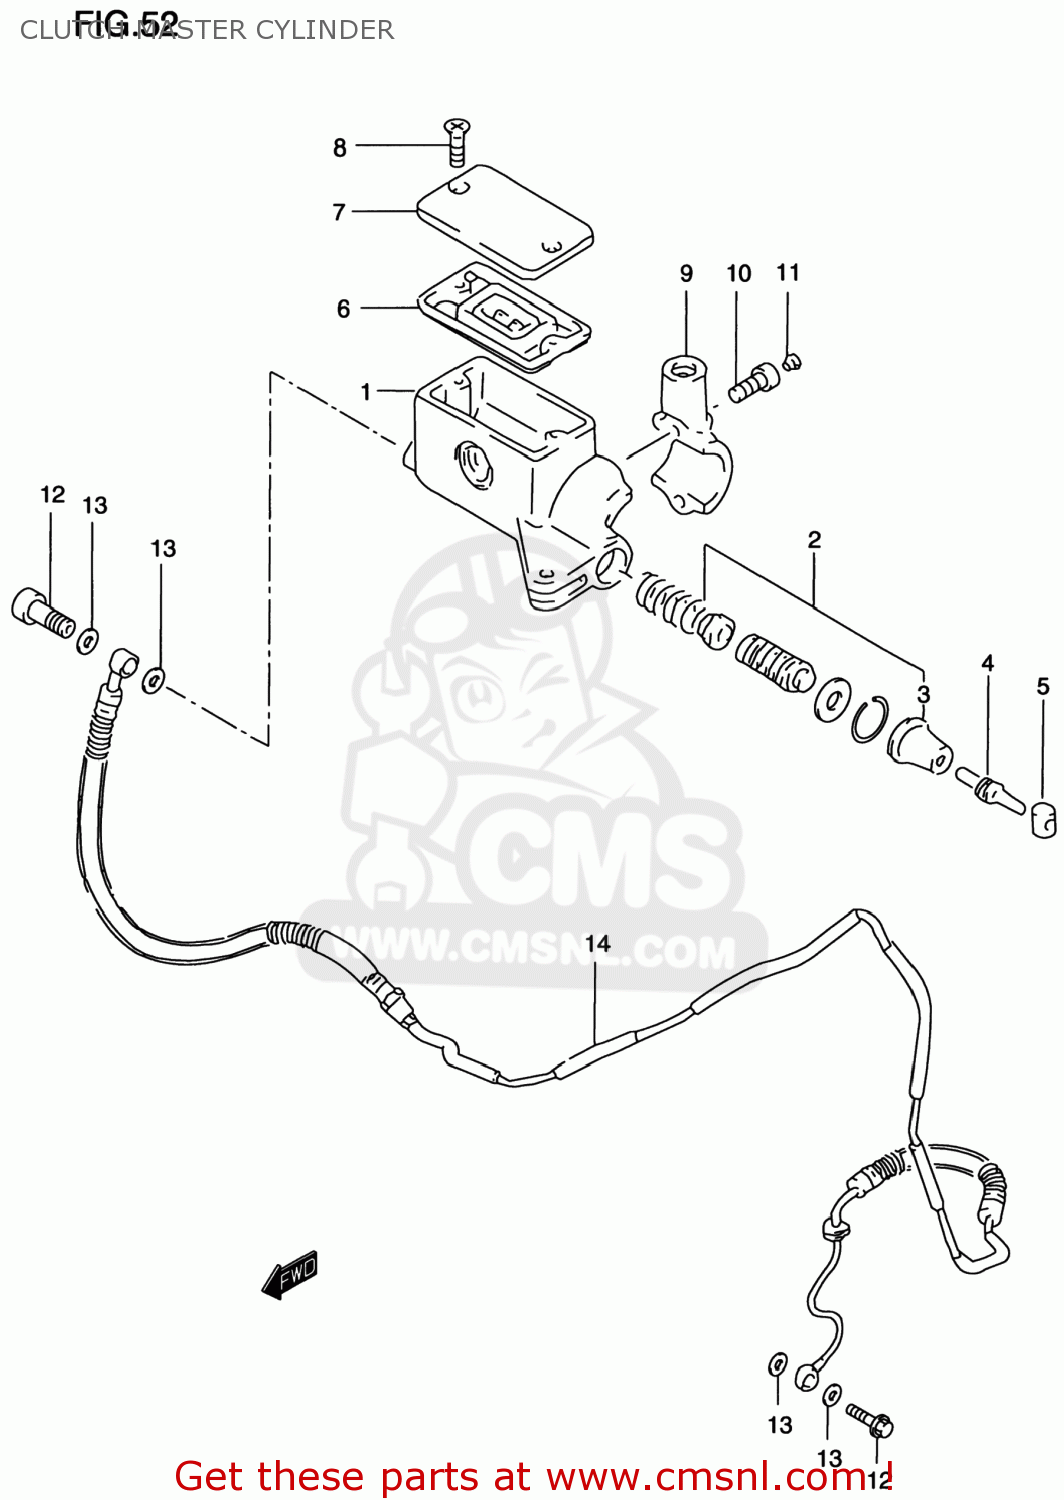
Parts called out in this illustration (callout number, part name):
1	CYLINDER ASSEMBLY,CLUTCH MASTER
2	PISTON & CUP SET
3	BOOT
4	PUSH ROD
5	BUSH
6	7
7	CAP
8	SCREW
9	HOLDER
10	BOLT
11	CAP(OD:10)
12	BOLT UNION
13	WASHER(10X15X1.5)
14	HOSE ASSY,CLUTCH
